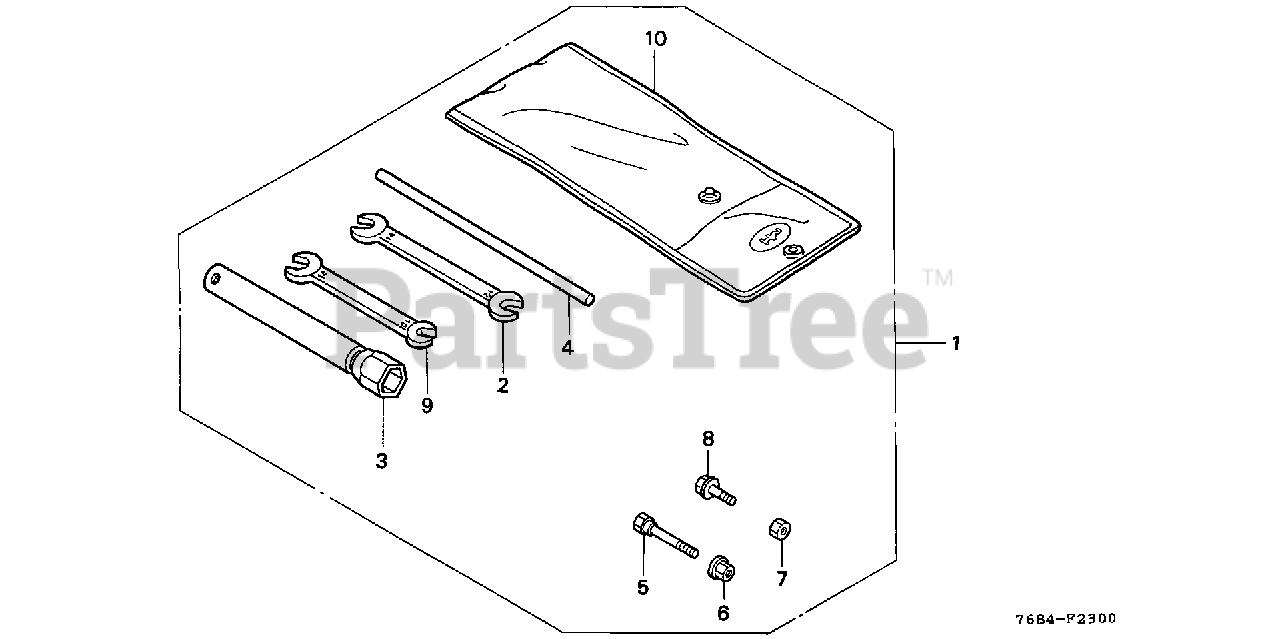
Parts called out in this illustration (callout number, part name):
2	SPANNER (12X14)
3	WRENCH, SPARK PLUG
4	HANDLE, BOX WRENCH
5	BOLT, LOCK
6	NUT, SELF-LOCK (6MM)
7	NUT, HEX. (6MM)
8	BOLT, FLANGE (6X16)
9	SPANNER (10X14)
